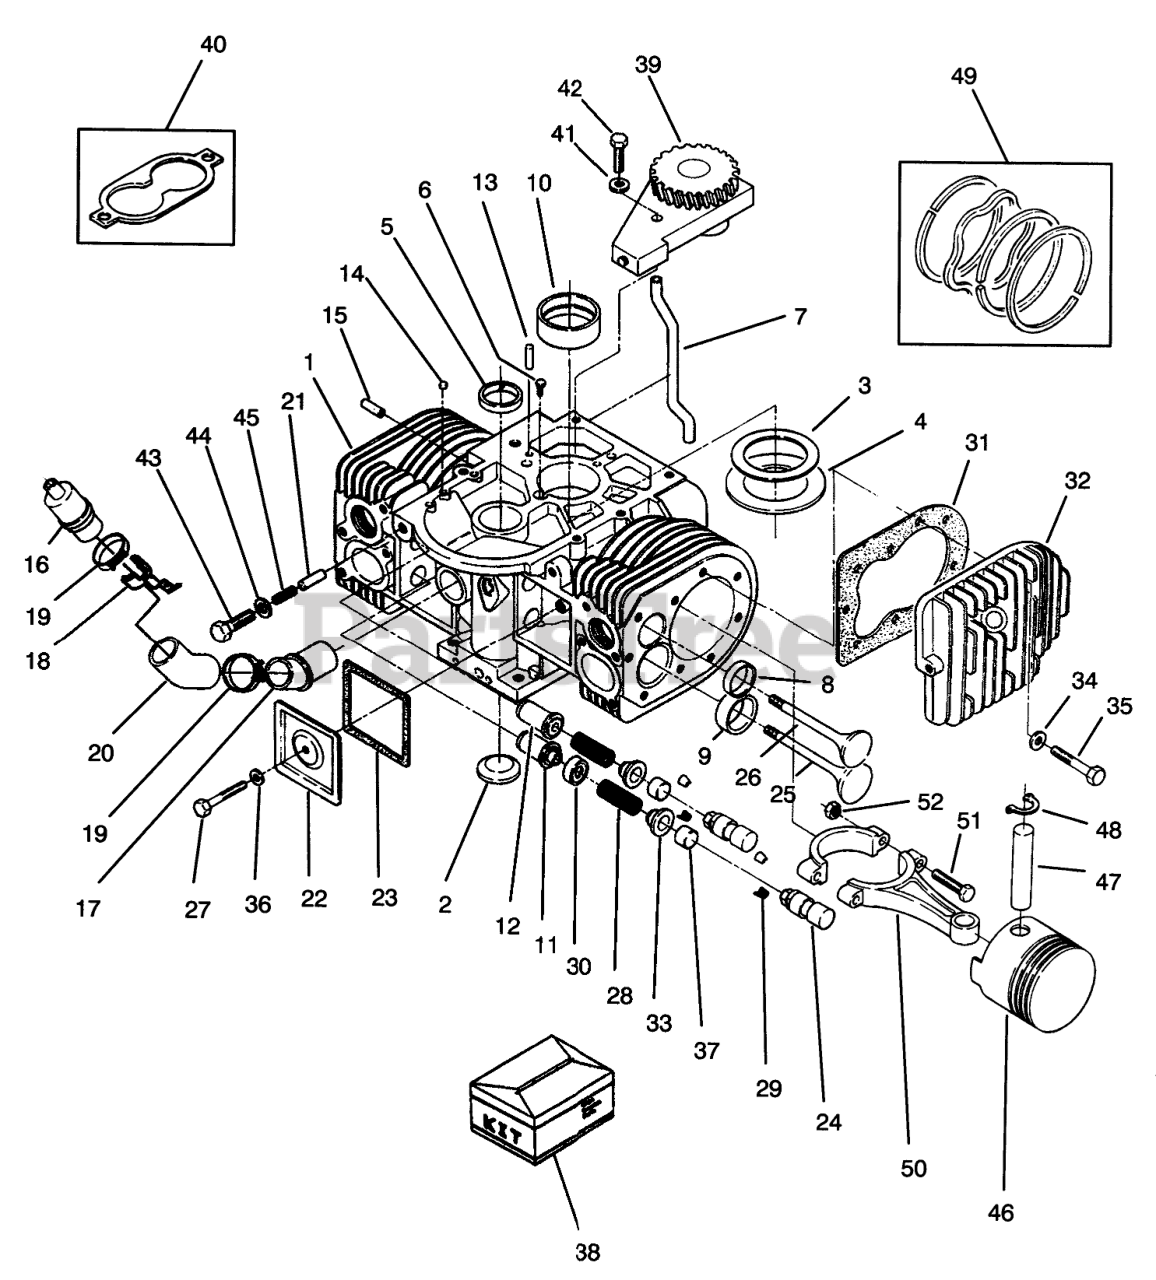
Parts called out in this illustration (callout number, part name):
1	BLOCK-ASS'Y CYLINDER
2	Plug
3	PISTON
4	WASHER
5	SLEEVE-BEARING
6	Screw
7	OIL TUBE
8	Standard
9	SEAT-INT VALVE (STD)
10	Bearing-Up Crankshaft Std
11	Guide-Intake Valve
12	Guide-ExhaustValve
13	Pin
14	PLUG-CORE HOLE
15	TUBE-PORT, VACUUM
16	Breather Tube
17	BREATHER-ADAPTER
18	BREATHER-MTG BRKT
19	HOSE-CLAMP
20	BREATHER-HOSE
21	DOWEL-PIN PLUG
22	Cover-Valve
23	BRG CUP & CONE RET
24	TAPPET
25	Intake Valve
26	Exhaust Valve
27	HHCS 1/4-20 X 1 3/4
28	Spring
29	VALVE SPRING LOCK
30	Seal
31	GASKET
32	Right Side
33	Washer
34	WASHER
35	Bolt
36	WASHER
37	Cap-Valve
38	KIT - GASKET
39	Pump-Oil
40	Kit-Oil Pump Gasket
41	Washer
42	Bolt
43	SCREW-HH
44	WASHER
45	SPRING
46	Standard
47	Pin-Piston
48	Piston Pin
49	RING SET
50	CONNECTING ROD W/NUT
